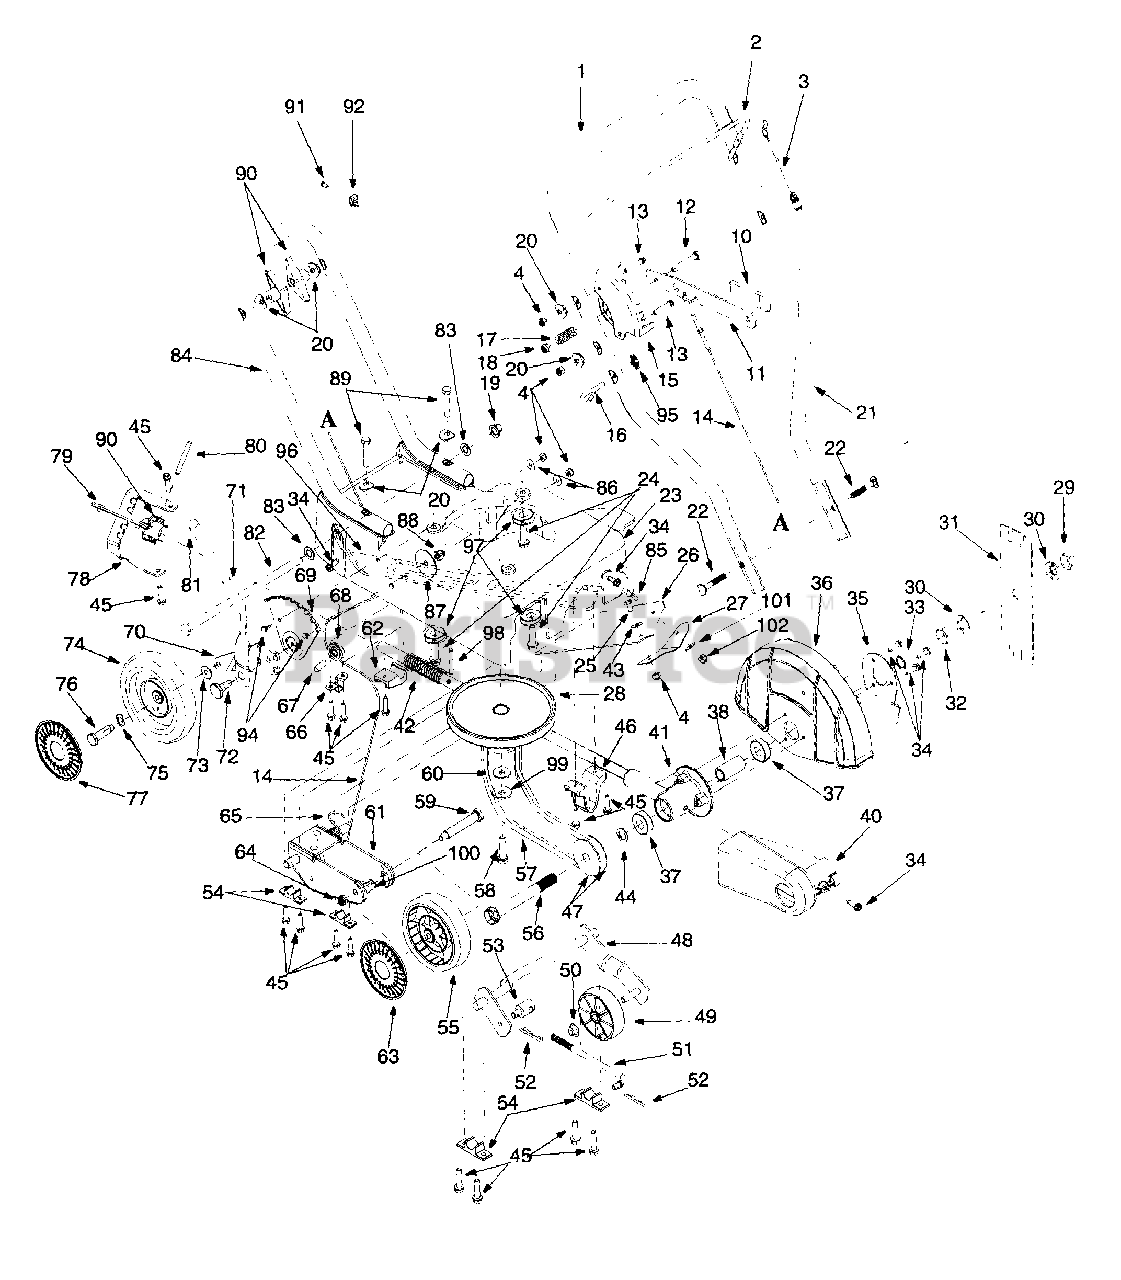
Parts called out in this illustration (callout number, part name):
1	Foam Grip
3	Control Cable 34" B & S (Const. Spd.)
4	Hex Lock Nut 1/4-20
10	Depth Lever Grip
12	Hex Screw 5/16-18 x 2.0 Lg.
13	Thrust Screw 1/4-20 x 1.5
14	Depth Cable
15	Depth Bracket
16	Eye Bolt 1/4-20
17	Compression Spring .550 O.D. x 1.3
18	Hex Lock Nut 5/16-18
19	Push Cap
20	Washer .320 ID x .93 O.D.
23	Edger Base Ass'y
24	Tapp Screw w/Hex Lock Wash 3/8-16
25	Hex Screw 1/4-20 x .50 Lg.
26	Discharge Shield Deflector
27	Deflector Keeper
28	Engine Pulley
29	Hex Jam Nut 5/8-18
30	Bell Washer .63 I.D. x 1.25 O.D. x .18
32	Hex Jam Nut 5/8-18
33	Spacer .628 x .875 x .545 Lg.
34	Hx Scr. w/Wash.: TT: 1/4-20 x .750 Lg.
37	Ball Bearing .62 I.D. x 1.38 O.D. x .4
38	Spacer .628 x .875 x 1.818 Lg.
40	Belt Guard
41	Spindle w/Insert
42	Compression Spring: Arbor
43	Flat Washer .283 I.D x .75 O.D. x .030
44	Flat Washer .635 I.D. x .93 O.D. x .06
45	Hex Screw w/Wash 1/4
46	Front Rod Handler
47	Pulley
50	Push Cap
51	Rod 5/16-24
52	Cotter Pin .072 x 1.12
53	Ferrule 5/16-24 x .312
54	Black Bushing .515 Dia x .62
55	Wheel 7 x 1.7 Aero Gray
56	Hex Bolt 5/8-18 x 5.25 Lg.
57	V-Belt
58	Hex Screw: 3/8-24 x 1.50 Lg.
59	Shoulder Screw .500 x 2.62: 3/8-16
60	Flat Washer .38 OD x 1.38 OD
61	Front Wheel Brkt Ass'y.
62	Rear Rod Handler
63	Hubcap: Spoke w/Hole Gray
64	Jam Lock Nut 3/8-16
65	Torsion Spring
68	Cable Roller Pulley
69	Index Plate
70	Pivot Arm
71	Spring Lever
72	Shoulder Bolt .500 x .434 Lg.
73	Bell Wash. .401 ID. x .870 OD. x .063
74	Wheel: 8 x 1.7 Aero Gray
75	Wave Washer .510 I.D. x .750 O.D.
76	Shoulder Bolt .498 x 1.445: 3/8-16
77	Hubcap: Radial Spoke Gray
78	Tilt Bracket
79	Adj. Lever Ass'y
80	Pin 1/4 x 2.0" Lg.
81	Foam Grip
83	Flat Wash. .531 I.D. x .875 O.D. x .06
86	Flat Wash. .285 ID x 1.25 OD x .06
87	Flat Wash. .406 ID x 1.92 OD x .06
88	Hex Lock Nut 3/8-16
89	Hex Screw 5/16-18 x 1.75 Lg.
90	Torsion Spring
90	Wing Knob Nut 5/16-18
91	Hex Scr. w/Wash.:T: #10-32 x .625 Lg.
92	Clamp B&S Throttle
94	Screw Std. 1/4-20 x .75 Lg.
95	Handle Knob
98	Roll Pin
99	Bell Washer .396 ID x 1.14 OD
100	Spacer .520 ID x .860 Lg.
101	Lock Washer 1/4
102	Hex Nut 1/4-20
